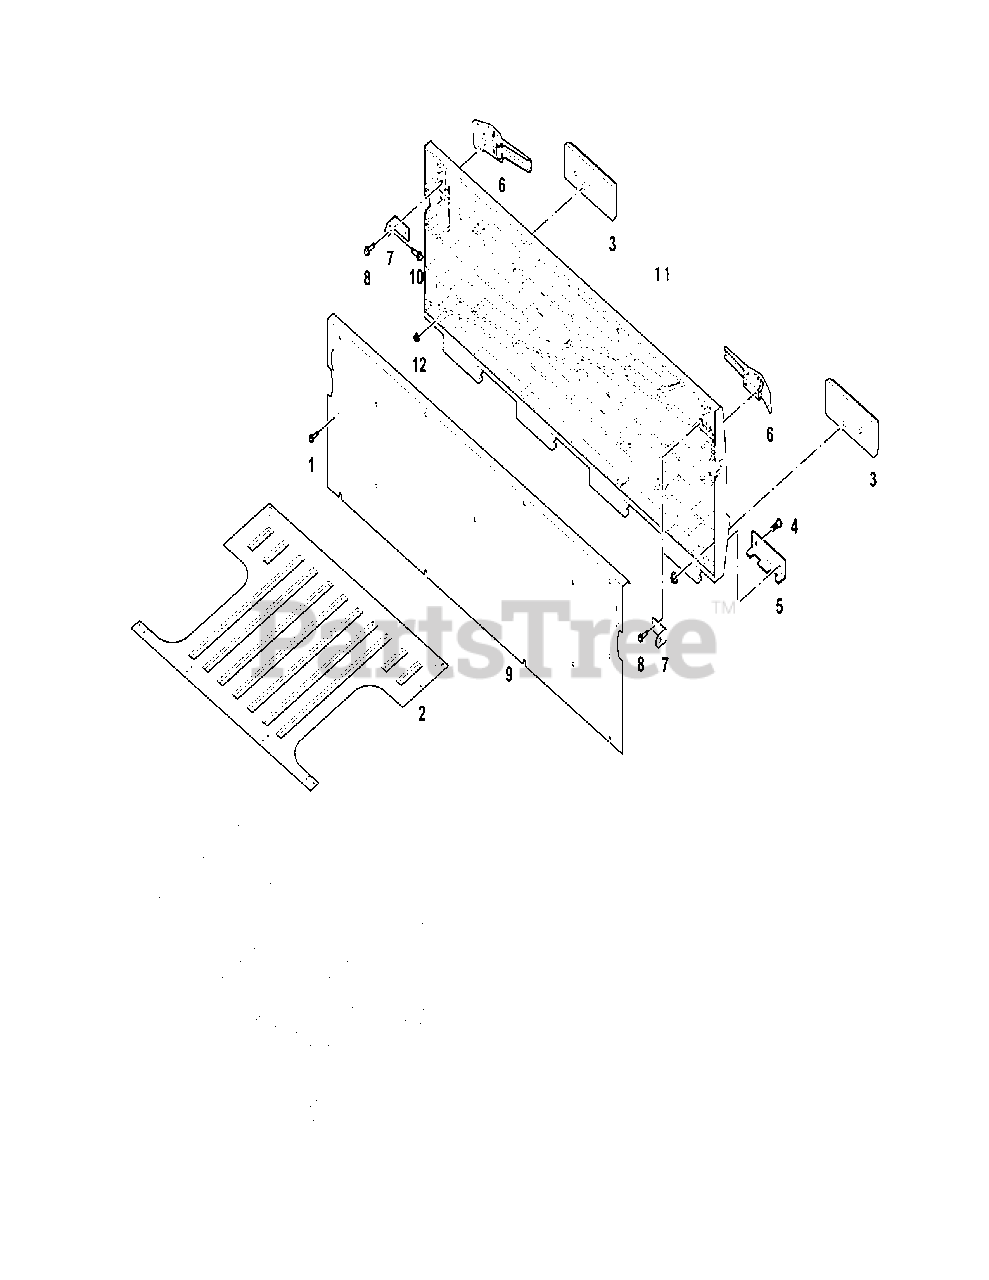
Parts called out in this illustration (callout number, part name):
1	Cross Small Plate Head Tapping Screw St4.8×13
2	Cargo Bed Rubber
3	Rear Reflector Assy
4	Self Tapping Screw,Cross Pan Headed St4.8×13
5	Pulling Board, Cargo Bed Tailgate
6	Cargo Bed Tailgate Locker
7	Cable Hook
8	Hexagon Flange Bolt M6×20
9	Cargo Bed Door Assy
10	Hexagon Flange Bolt M6×12-10×4
11	Decorative Board, Cargo Bed Door
12	Hexagon flange nut M5
